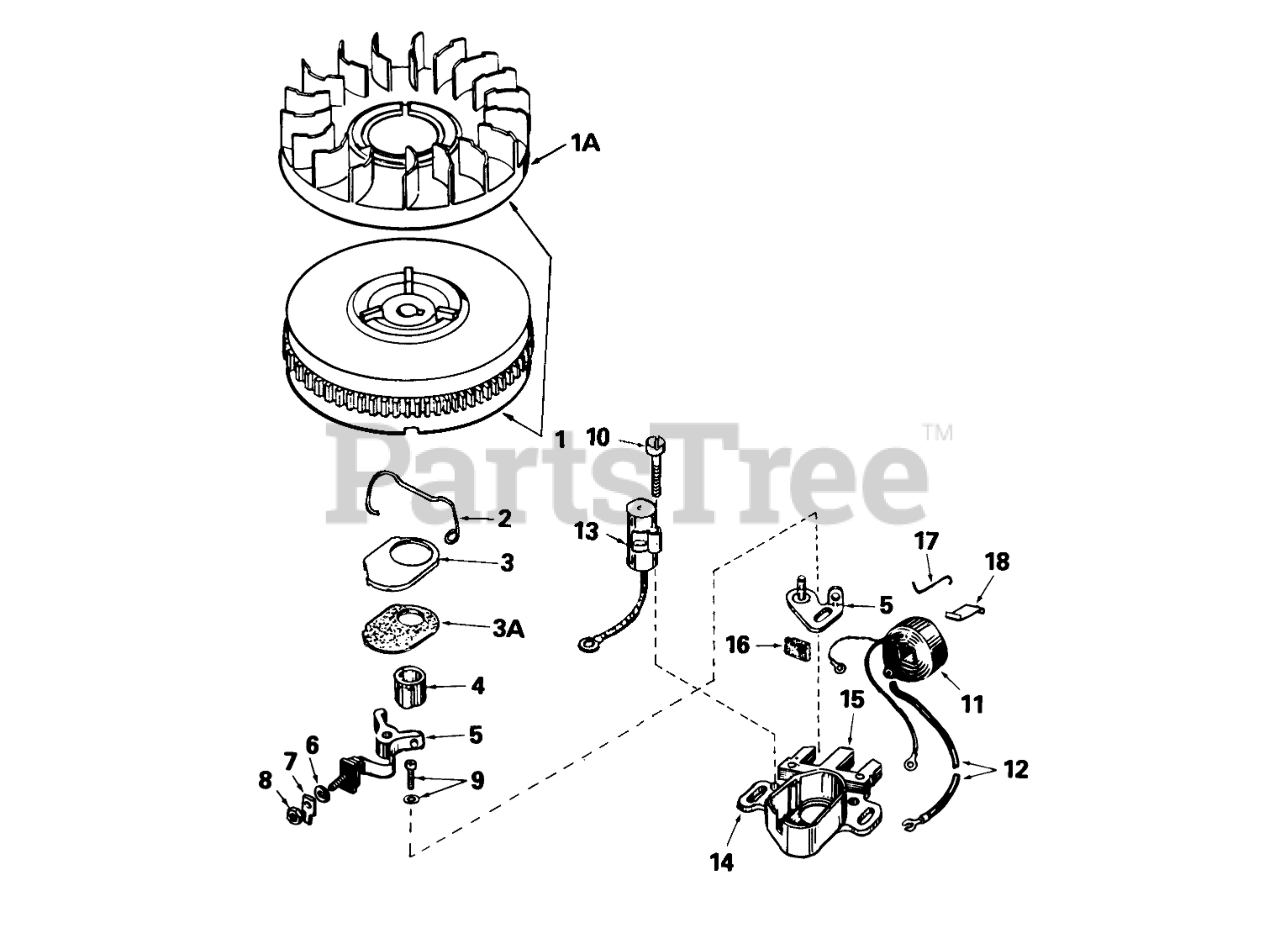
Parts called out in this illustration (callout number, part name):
1	Flywheel (Incl. #1A)
1A	Fan
2	Spring Breaker Box
3	Cover-Dust
3A	Gasket-Dust Cover
4	Cam-Breaker
5	Breaker Assy.
6	Washer
7	Terminal, Ground
8	DECAL
9	Breaker Screw
10	Condenser Screw
11	Coil Assy. (Incl. #12)
12	Wire, Lead
13	Condenser
14	Core & Plate
15	Stator Assy. (Incl. #2, 3, 3A, 5 thru 14, 16 & 17)
16	Felt,Cam Wiper
17	Clip, Coil
